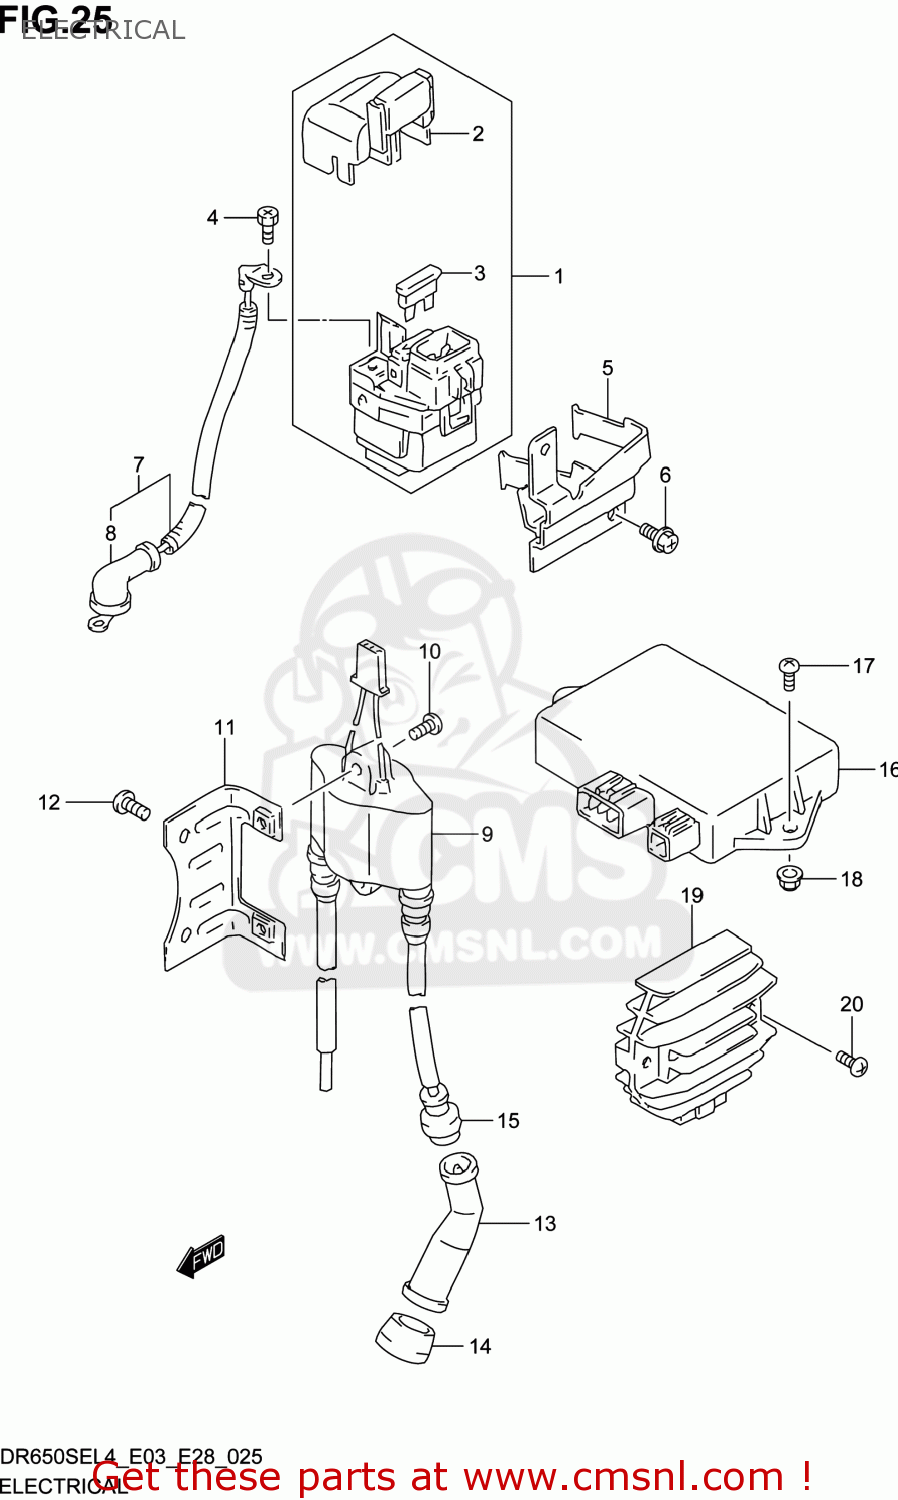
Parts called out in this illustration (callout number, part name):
1	RELAY ASSY,STARTING MOTOR
2	COVER,STARTER RELAY
3	FUSE(30A)
4	SCREW(6X8)
5	BRACKET,STARTING MOTOR RELAY
6	SCREW
7	WIRE,STARTER MOTOR
8	CAP,STARTER MOTOR LEAD
9	COIL ASSY,IGNITION
10	SCREW
11	BRACKET,IGNITION COIL
12	SCREW
13	CAP,SPARK PLUG
14	SEAL,SPARK PLUG
15	SEAL,HIGH TENSION CORD
16	CDI UNIT
17	SCREW
18	NUT
19	RECTIFIER ASSY
20	SCREW
